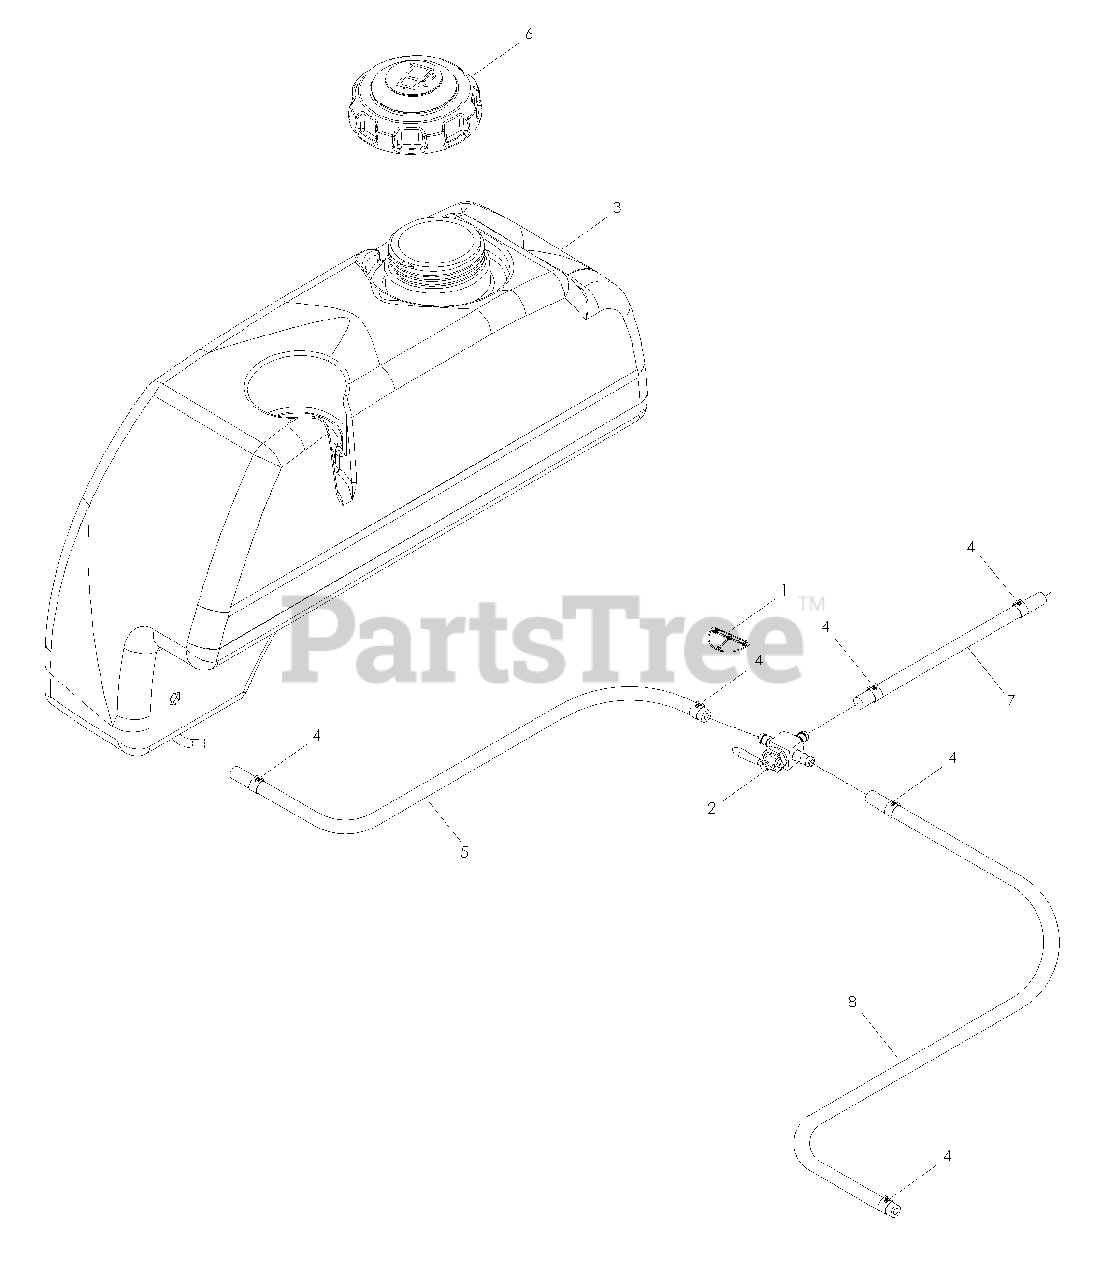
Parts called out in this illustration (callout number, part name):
1	DECAL-FUEL VALVE
2	VALVE-FUEL
3	TANK-FUEL RIGHT
3	TANK-FUEL LEFT
4	CLAMP-HOSE
5	LINE, FUEL
6	CAP, FUEL
7	LINE, FUEL
8	LINE, FUEL
